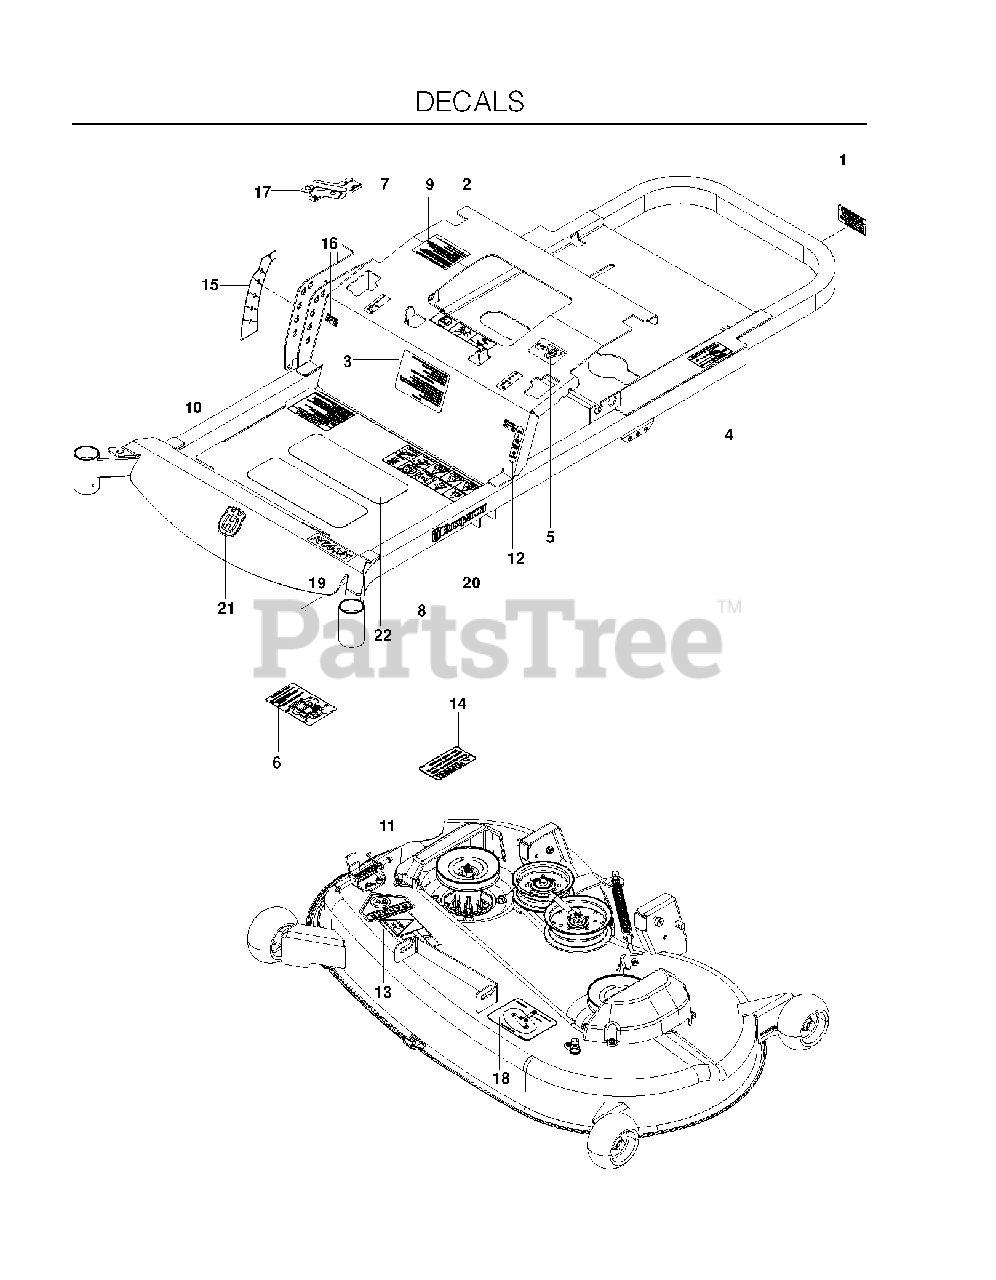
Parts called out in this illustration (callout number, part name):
1	DECAL, PROP. 65
2	EURO DECAL-BATTERY WARNIN6
3	DECAL, START
4	DECAL, DO NOT TOW
5	DECAL, EXITING MOWER
6	DECAL, SERVICE
7	DECAL, MOTION CONTROL
8	DECAL, SAFETY WARNING
9	DECAL, CUSTOMER RESPNSIBILITY
10	DECAL, WARNING
11	DECAL, CPSC
12	DECAL, PARK BRAKE
13	DECAL, EURO SEVERING
14	DECAL, CAUTION
15	DECAL, HEIGHT
16	DECAL, F.S.T.
17	DECAL, CTRL PANEL, HUSQ
18	DECAL, BELT ROUTING
19	DECAL, RZ4623
20	RP.DECAL.BADGE.170MM.TEXTLOGO
21	DECAL.AUGER.HUSQ.CROWN.SNOW
22	ANTI-SKID PAD
